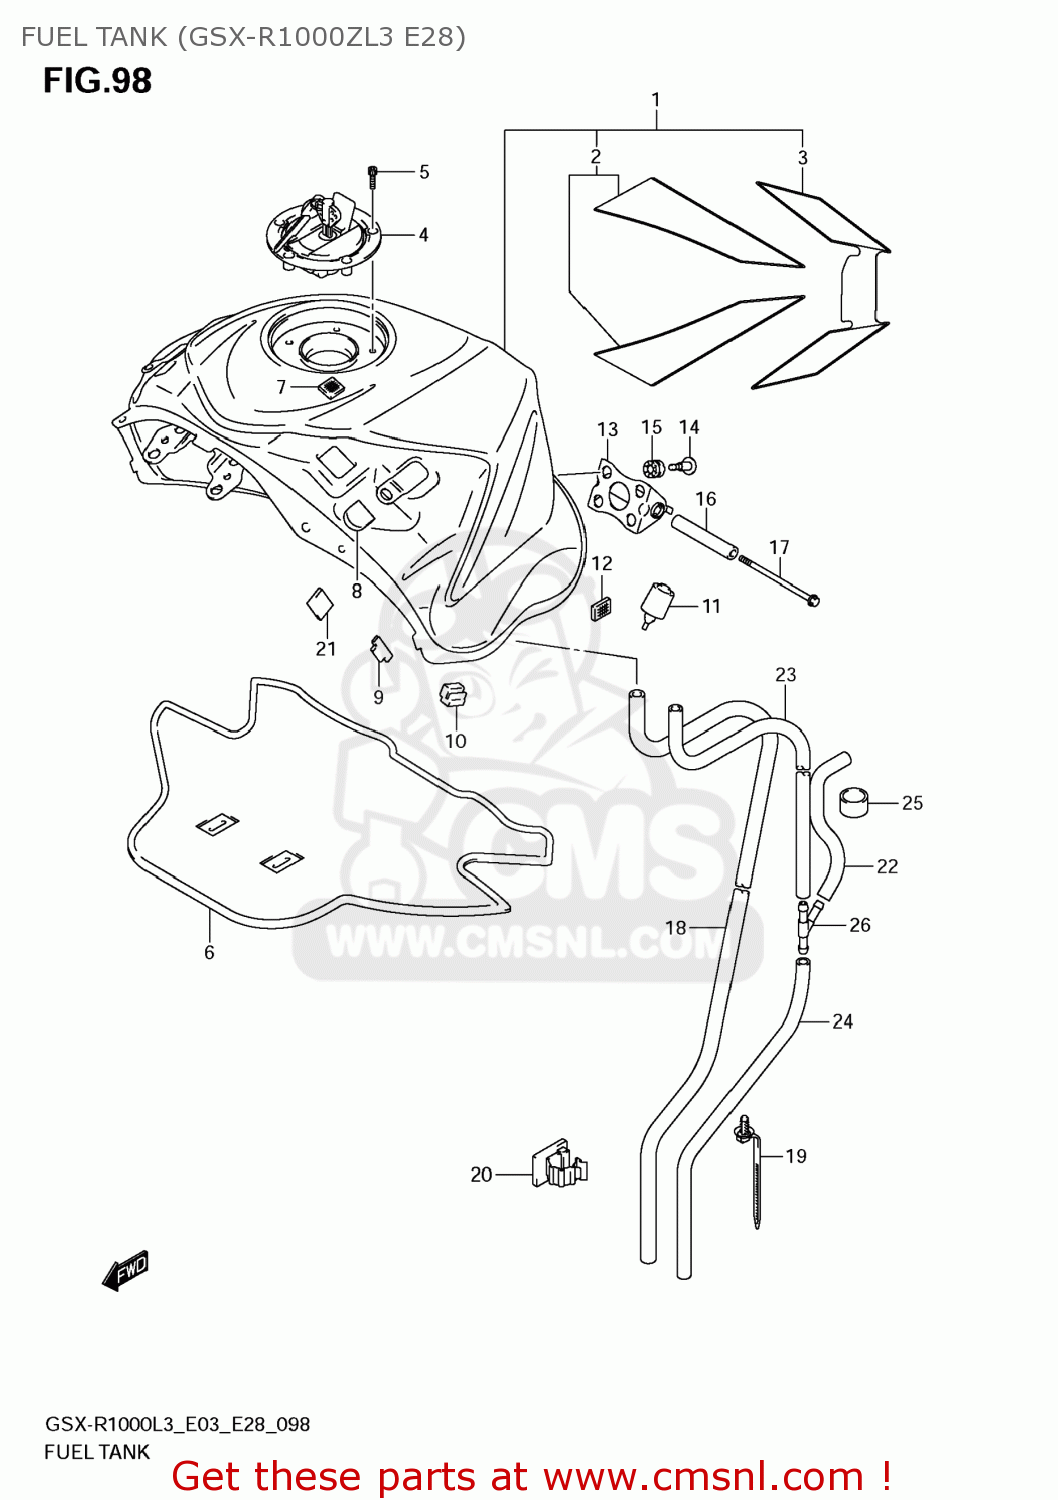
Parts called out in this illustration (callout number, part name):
1	TANK ASSY,FUEL(WHITE)
2	TAPE SET,FUEL TANK
3	TAPE,FUEL TANK CTR
4	CAP SET,FUEL TANK
5	BOLT(5X20)
6	SHIELD,FUEL TANK HEAT
7	FASTENER
8	CUSHION
9	CUSHION,FUEL TANK COVER
10	CUSHION,FUEL TANK SIDE
11	CUSHION,FUEL TANK RR
12	FASTENER
13	BRACKET,FUEL TANK NO.1
14	SCREW(6X22)
15	CUSHION
16	SPACER,FUEL TANK RR
17	BOLT(6X110)
18	HOSE,FUEL TANK WATER DRAIN
19	CLAMP(L:154)
20	CLAMP
21	PAD
22	HOSE,TANK BREATHER NO.2
23	HOSE,FUEL TANK BREATHER NO.1
24	HOSE,FUEL TANK BREATHER NO.2
25	HOSE(12X16X600)
26	3 WAY
